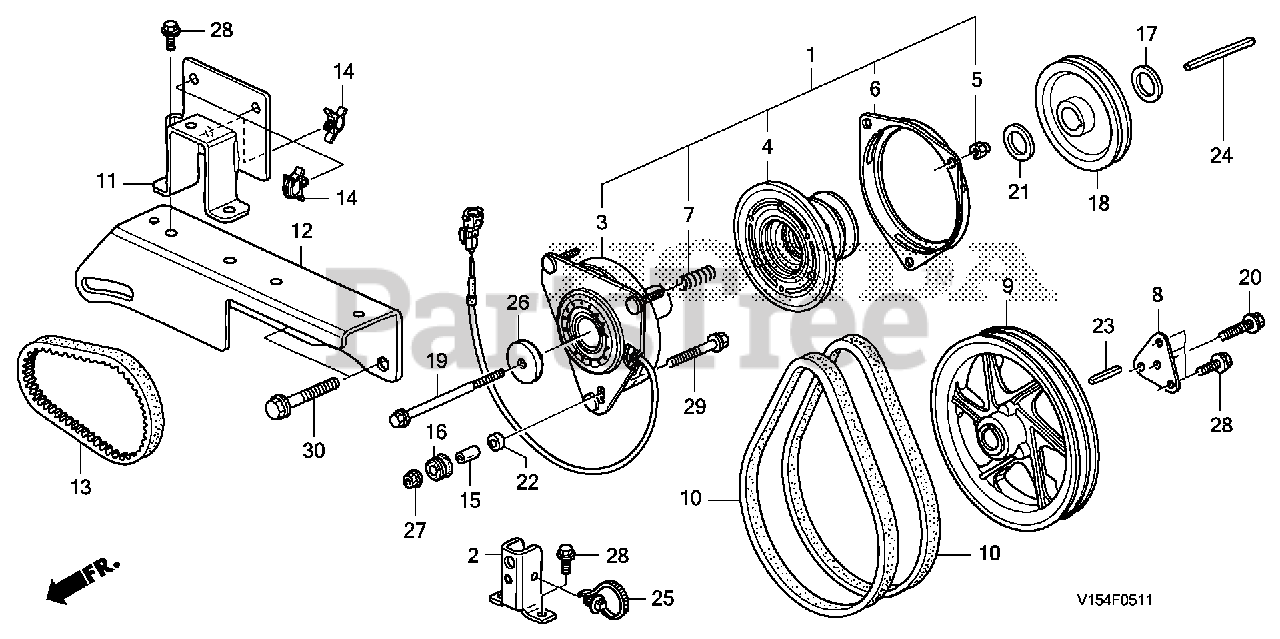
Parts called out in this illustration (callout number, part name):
1	CLUTCH-BRAKE ASSY.
2	STOPPER, CLUTCH
5	NUT, HEX. (3/8-24UNF)
6	COVER, BRAKE
7	SPRING, RETURN
8	PATCH, PULLEY
9	PULLEY, AUGER DRIVEN
10	V-BELT (LB-36)
11	BRACKET, ALTERNATOR
12	STAY, ALTERNATOR
13	BELT, ALTERNATOR
14	CLIP, WIRE HARNESS
15	COLLAR, STEP (LOWER)
16	BUSH, RUBBER (NOT AVAILABLE)
17	COLLAR, DISTANCE (25MM)
18	PULLEY, ENGINE
19	BOLT, UBS (8X95) (NOT AVAILABLE)
20	BOLT, FLANGE (8X20)
21	WASHER (35MM)
22	COLLAR, MUFFLER MOUNTING
23	KEY (7X7X42)
24	KEY (7X7X103)
25	CLIP, WIRE HARNESS (110MM) (7MM HOLE) (GREEN)
26	COLLAR, CLUTCH
27	NUT, FLANGE (8MM)
28	BOLT, FLANGE (8X16)
29	BOLT, FLANGE (8X38)
30	BOLT, FLANGE (10X16)
